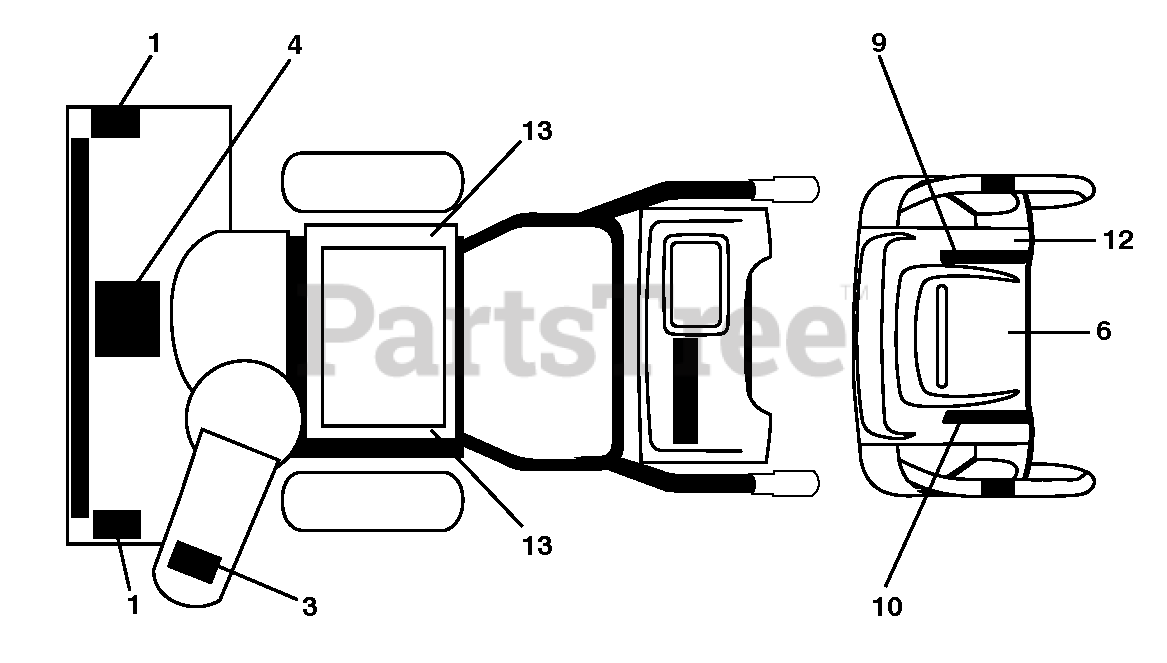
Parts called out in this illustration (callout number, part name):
1	DECAL.AUGER.SAFETY.
3	DECAL.CHUTE.SAFETY.
4	DECAL.AUGER."
9	DECAL CONSOLE DECAL DECAL.SNOW
10	DECAL CONSOLE DECAL DECAL.SNOW
12	DECAL.CONSOLE.HAND.WARMER
13	DECAL.BELT.GUARD.
